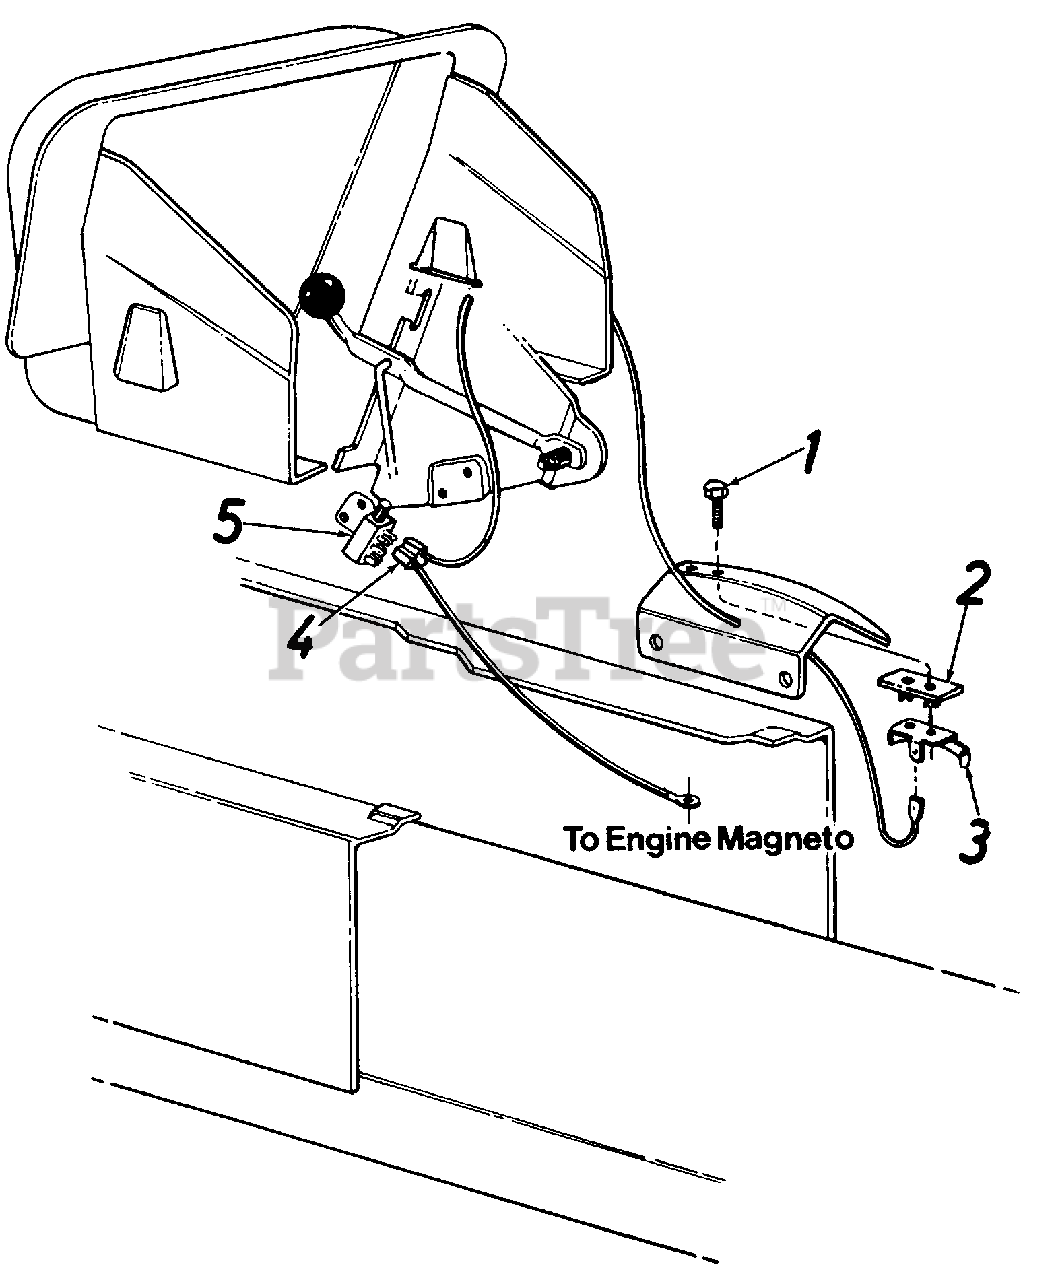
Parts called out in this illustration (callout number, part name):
1	Hex Wash. Hd. Screw #8 x .50" Lg.
2	Insu lator Nut Plate
3	Spring Switch
4	Reverse Lockout Wire Harness
5	Safety Switch
